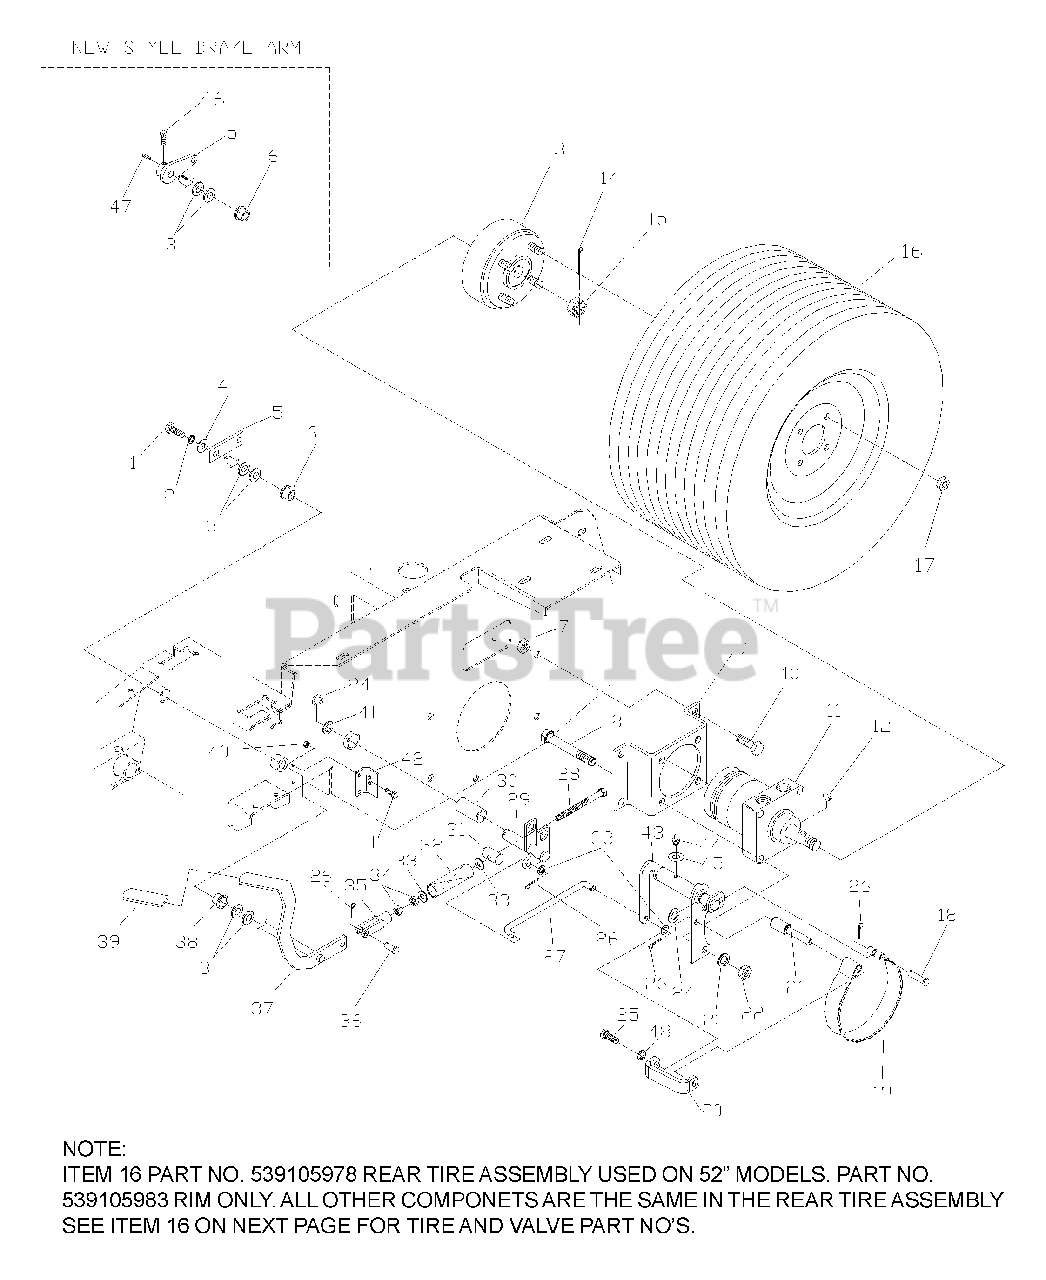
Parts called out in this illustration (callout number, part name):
1	HCS 1/4C X 3/4
2	1/4 LOCK WASHER
3	WASHER 7/16 SPRING
4	1/4 FLAT WASHER
5	ARM, PARK BRAKE
7	NUT 1/2C NYLOC
8	HCS 1/2C X 2.75
9	MOTOR STANDOFF
10	HCS 1/2C X 1.25
11	WHEEL MOTOR
12	WOODRUFF KEY
13	HUB W/ BRAKE DRUM
14	COTTER PIN
15	CASTLE NUT
16	REAR TIRE ASM OFFSET RIM
16	REAR TIRE ASM
16	RIM (OFFSET)
17	LUG NUT 1/2F
18	3/8 X 1.50 CLEVIS PIN
19	BRAKE BAND
20	SUPPORT BKT -
20	HCS 3/8C X 3 GD8
21	BAND PIVOT -
23	1/2 LOCK WASHER
24	E - RING 3/4
25	HCS 3/8 X 1.0 GD 8 -
25	NUT 3/8C CTR LOCK
26	COTTER PIN
27	BRAKE LINKAGE LT
27	BRAKE LINKAGE RT
28	HCS 3/8F SPECIAL
30	BRONZE BEARING
31	TRUNION PIN
33	3/8 SAE WASHER
36	3/8 X 1.125
37	BRAKE LEVER WLDMT
37	BRAKEARM WLDMT
40	1/4C LOCK NUT
41	MACH BUSHING 3/4
42	BRACKET
43	LEFT BRAKE BKT
43	RIGHT BRAKE BKT
44	ZERK
46	SETSCRW
47	KEY 1/4 X 875
48	WASHER 3/8 LOCK
